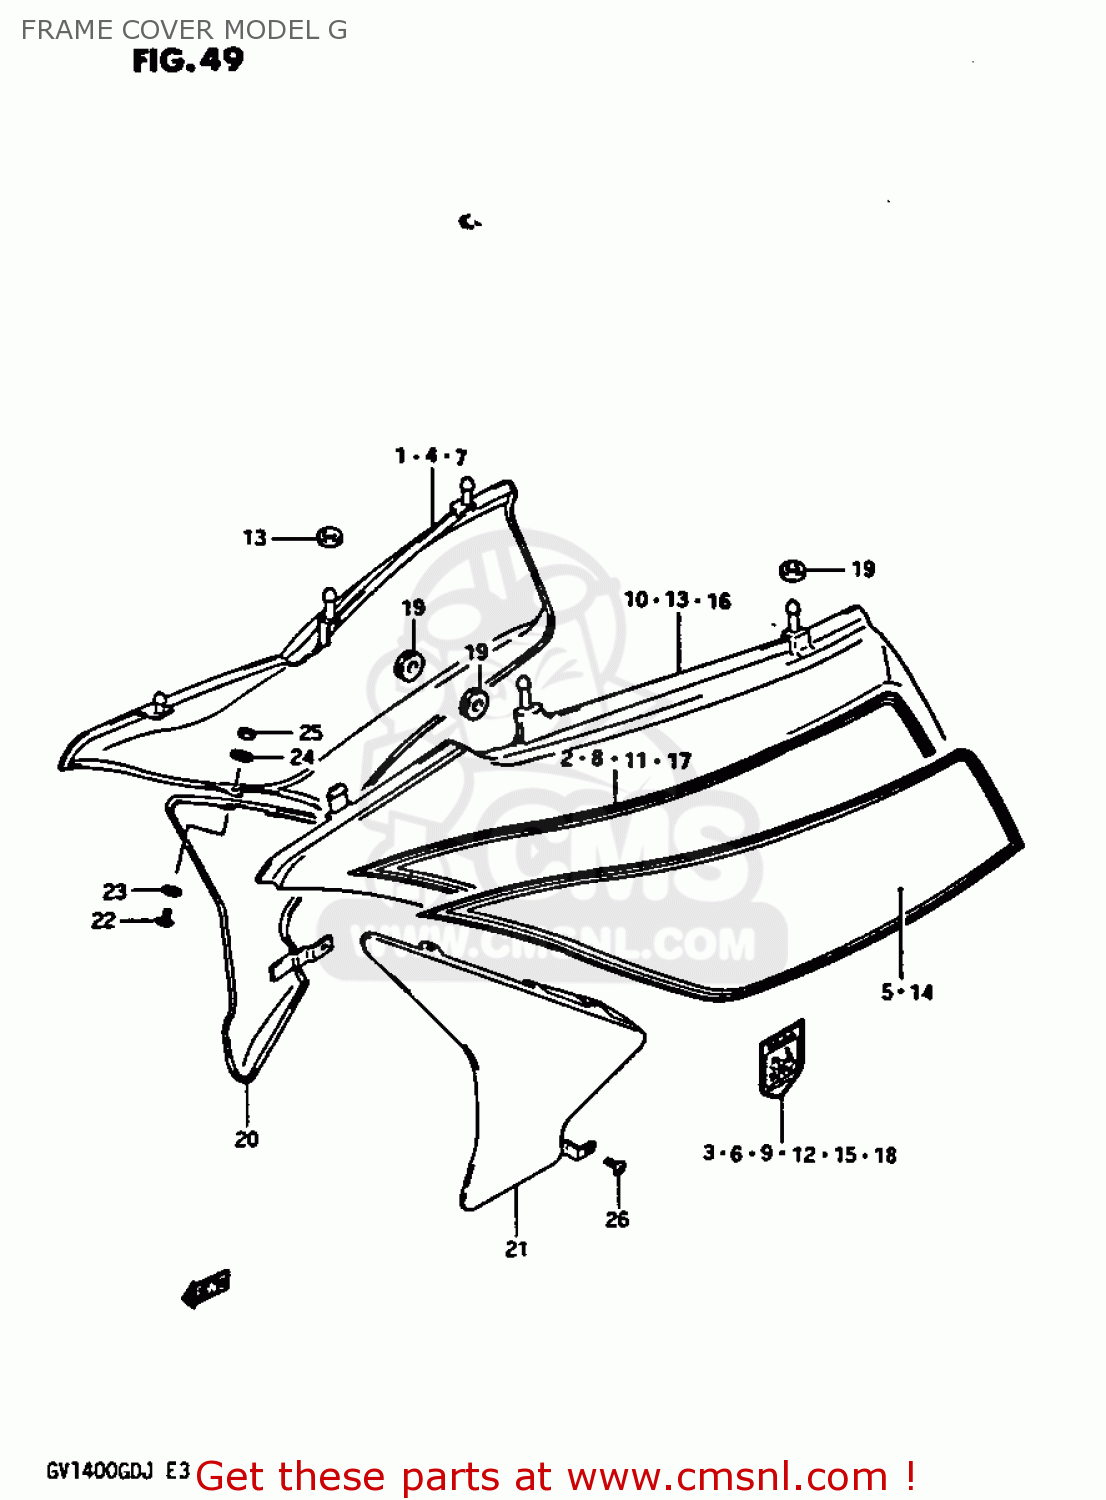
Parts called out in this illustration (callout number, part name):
1	COVER,FRAME,RIGHT
2	TAPE SET,FRAME COVER,RIGHT
3	EMBLEM,FRAME COVER
4	COVER,FRAME,RIGHT
5	TAPE SET,FRAME COVER
6	EMBLEM,FRAME COVER
7	COVER,FRAME,RIGHT
8	TAPE SET,FRAME COVER
9	EMBLEM,FRAME COVER
10	COVER,FRAME,LEFT
11	TAPE SET,FRAME COVER
12	EMBLEM,FRAME COVER
13	COVER,FRAME,LEFT
14	TAPE SET,FRAME COVER
15	EMBLEM,FRAME COVER
16	COVER,FRAME,LEFT
17	TAPE SET,FRAME COVER,LEFT
18	EMBLEM,FRAME COVER
19	CUSHION
20	COVER,UNDER,RIGHT
21	COVER,UNDER,LEFT
22	SCREW
23	WASHER
24	WASHER (6.7X16X1.8)
25	NUT 6MM
26	SCREW
